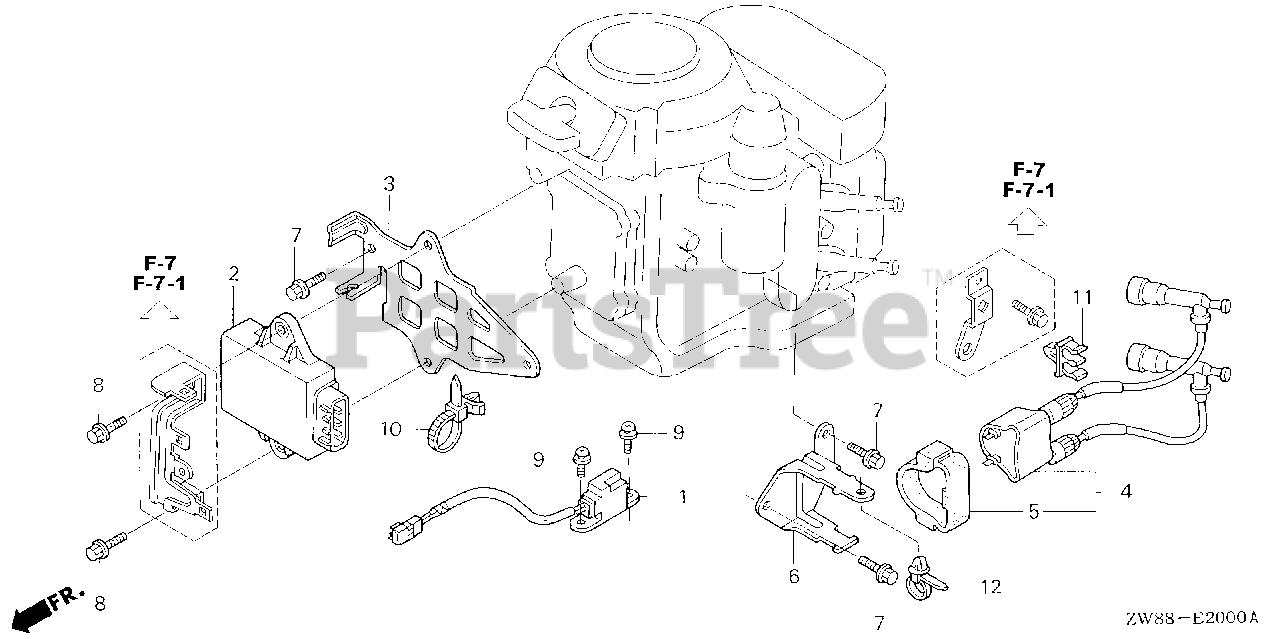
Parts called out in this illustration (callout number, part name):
1	COIL ASSY., PULSER
2	MODULE, IGNITION CONTROL (CDI)
3	PLATE, C.D.I.
4	COIL ASSY., IGNITION
5	SUSPENSION, IGNITION COIL
6	BRACKET, IGNITION COIL
7	BOLT, FLANGE (6X14) (CT200)
8	BOLT, FLANGE (6X25)
9	SCREW-WASHER (5X16)
10	STRAP, CABLE (118MM) (BLACK)
11	CLIP, FUEL TUBE
12	CLIP, HARNESS BAND (151.5MM) (NATURAL)
